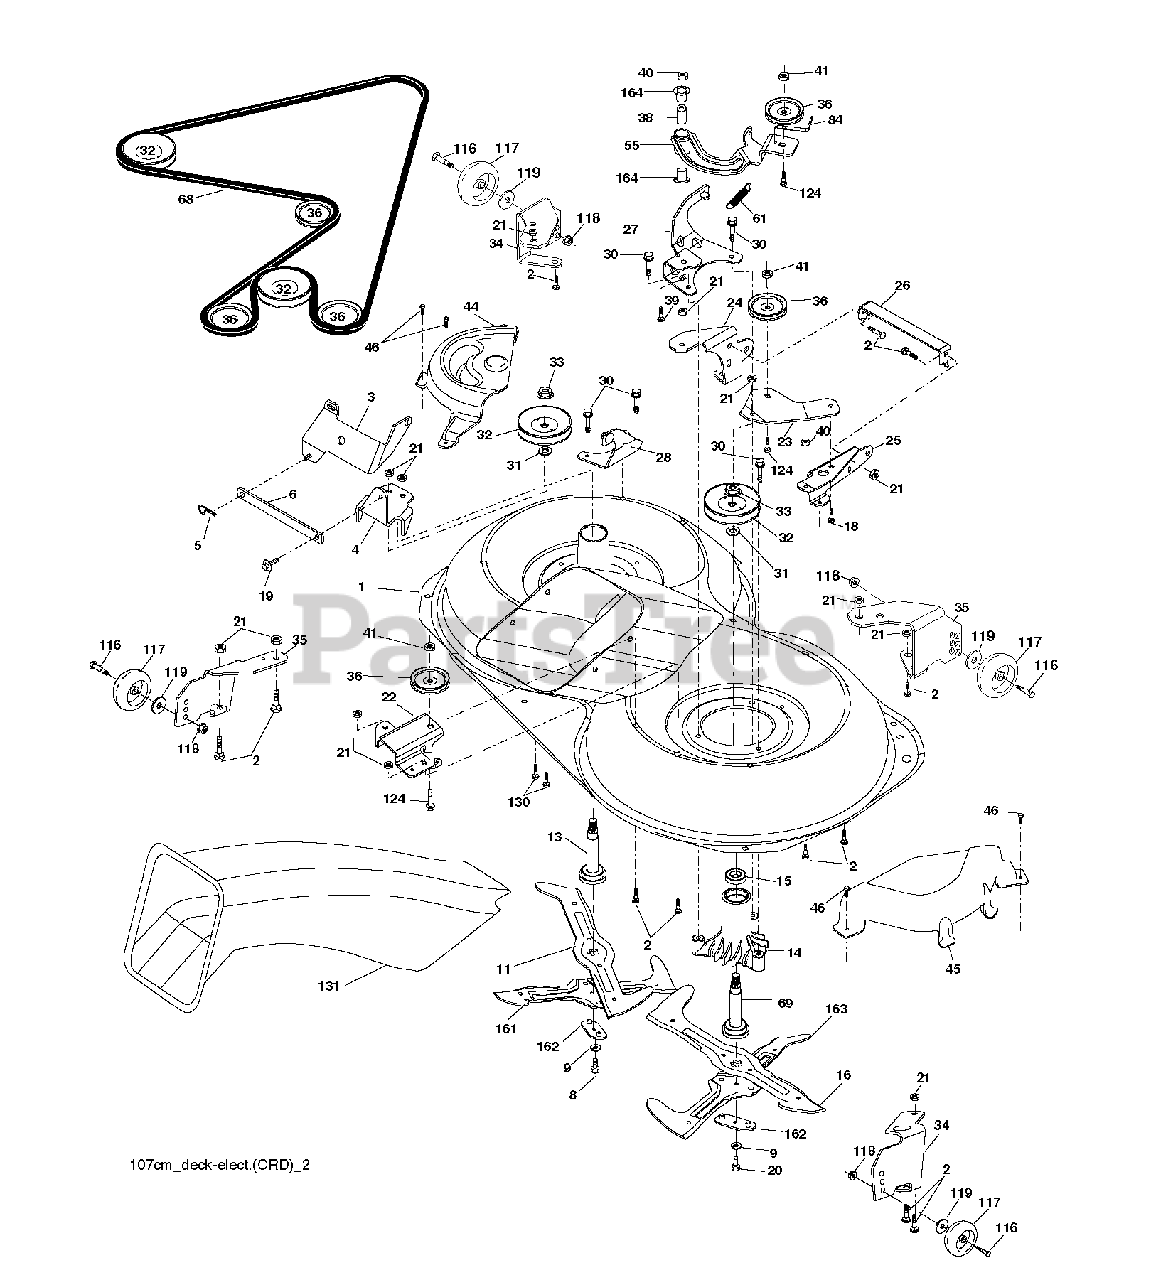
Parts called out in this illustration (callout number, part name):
2	BOLT
3	BRACKET
5	RETAINER-SPRNG RB
6	BAR SWAY
9	LOCKWASHER
11	BLADE.3N1.LH.CRD
13	SHAFT ASM VENT
14	HSG MANDREL
16	BLADE.3N1.RH.CRD
19	BOLT SHD 5/16-18
21	LOCKNUT
22	BRACKET
23	BRACKET
27	BRACKET
30	SCREW, WASHER HEAD
31	WASHER.SPACER.MANDREL
33	NUT.FLANGE.LOCK.TOP
36	PULLEY.IDLER.4.25
40	LOCKNUT
41	NUT LOCK FLG 3/8-16 UNC
45	MANDREL COVER
46	SCREW.1/4-20X5/8
55	ARM IDLER
68	HEX-BELT 107 MOWER
69	SHAFT.ASM.W/LWR.BRG.RH.THREAD
84	KEEPER, BELT IDLER
116	BOLT.SHOULDER.3/8-16X3-5/8
117	WHEEL. GUAGE RALLY
118	NUT LOCK FLG 3/8-16 UNC
124	BOLT.3/8-16X1.50
131	CHUTE BAGGER
164	BRNG T
